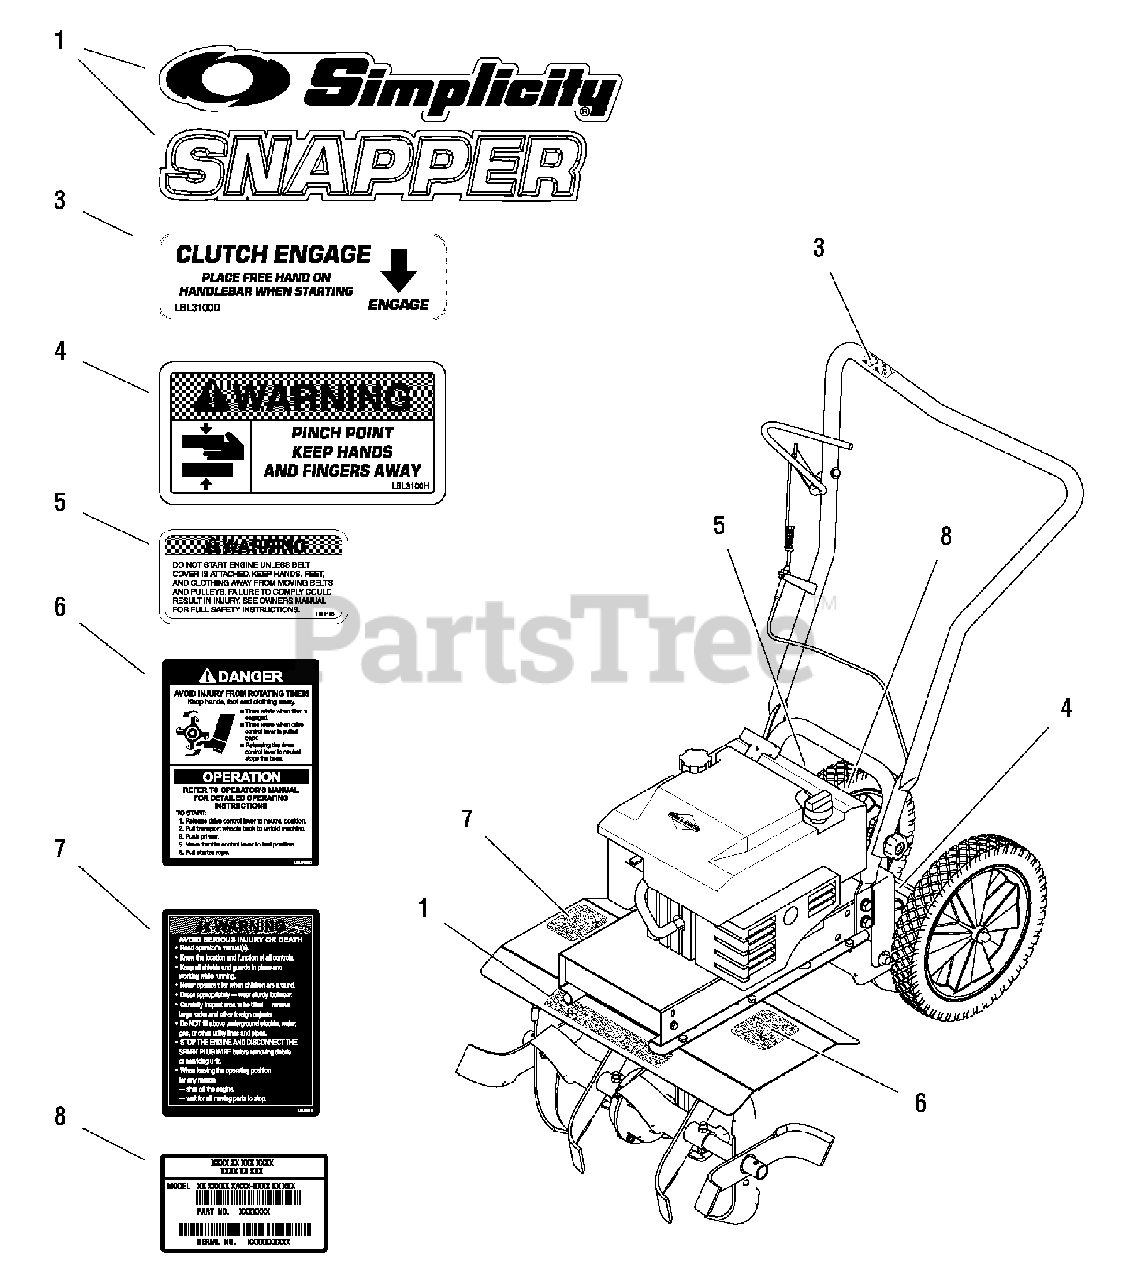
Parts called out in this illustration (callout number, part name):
1	DECAL, SIMPLICITY, w/Logo
1	DECAL, Snapper
2	DECAL SHEET, Common Warning Roticul Tillers
3	* DECAL, Clutch Engage
4	* DECAL, Warning Pinch Point
5	* DECAL, Warning, Belt Cover
6	* DECAL, Hood, Operator Instructions Label
7	* DECAL, Warning, Serious Injury
8	** DECAL, Serial Number
